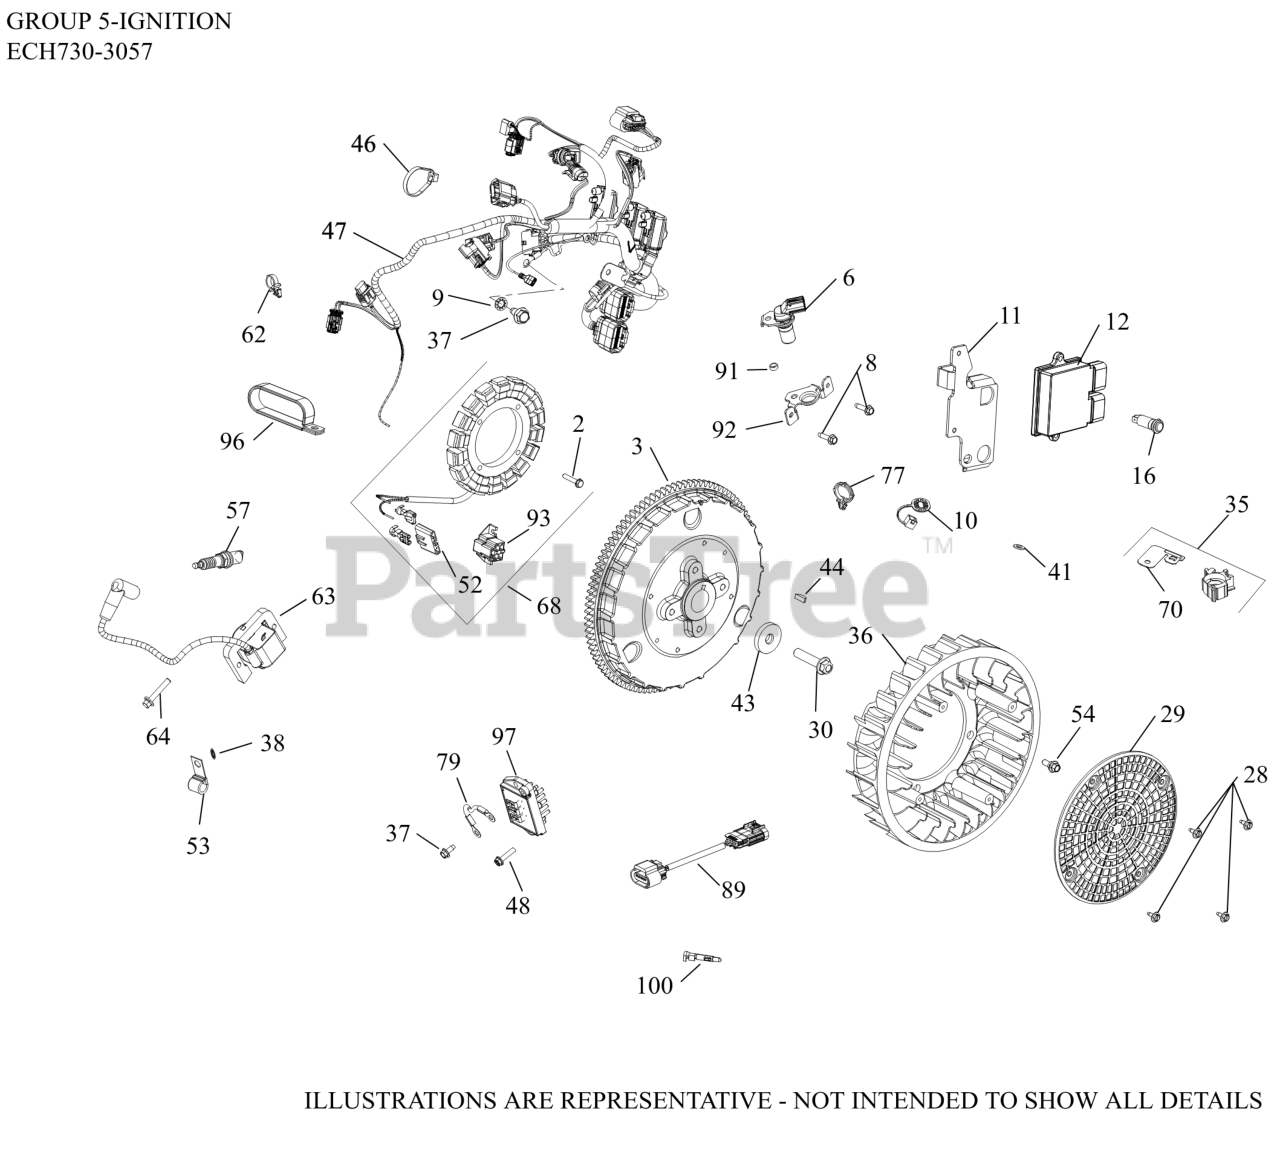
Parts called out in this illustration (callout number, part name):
2	SCREW, THREAD FORMING
3	FLYWHEEL, ASSEMBLY
6	SENSOR, SPEED
8	SCREW, THREAD FORMING
9	WASHER, INT TOOTH LOCK #10
10	CAP, CONNECTOR
11	BRACKET, ECU
12	MODULE, ECU
16	LAMP, INDICATOR (INCANDESCENT)
28	SCREW, SEMS DOG POINT
29	SCREEN,GRASS LOW PRFLE W/O HOLE
30	SCREW, FLG M10X1.5X45-USE 25 086 361-S
35	KIT, MOUNTING CLIP
36	FAN-USE 24 755 253-S
37	SCREW, THREAD FORMING
38	WASHER, INT TOOTH LOCK 1/4"
41	WASHER, FLAT 1/4" (O.D. 1/2")
43	WASHER, FLAT 13/32"
44	KEY, 3/16" X 5/8"
47	HARNESS, WIRING ASSEMBLY
48	SCREW, HEX FLANGE HI-LO
52	CONNECTOR
54	BOLT, SHOULDER
57	SPARK PLUG, RFI
62	CLIP, SNAP-IN-USE 25 018 05-S
63	COIL, IGNITION - EFI (RFI/EMC)
64	SCREW, FLG (BLACK) M6X1.0X34
68	KIT, 25 AMP STATOR ASSY.
68	KIT, 25 AMP CONVERSION-DISCONTINUED
70	CLIP USE 25 154 21-S
77	RETAINER, WIRE HARNESS
89	HARNESS ASSEMBLY, WIRING
92	BRACKET, SENSOR
93	CONNECTOR
96	CLAMP, INSULATED DOUBLE
97	REGULATOR, RECT (20-30AMP, FW W/OVP)
